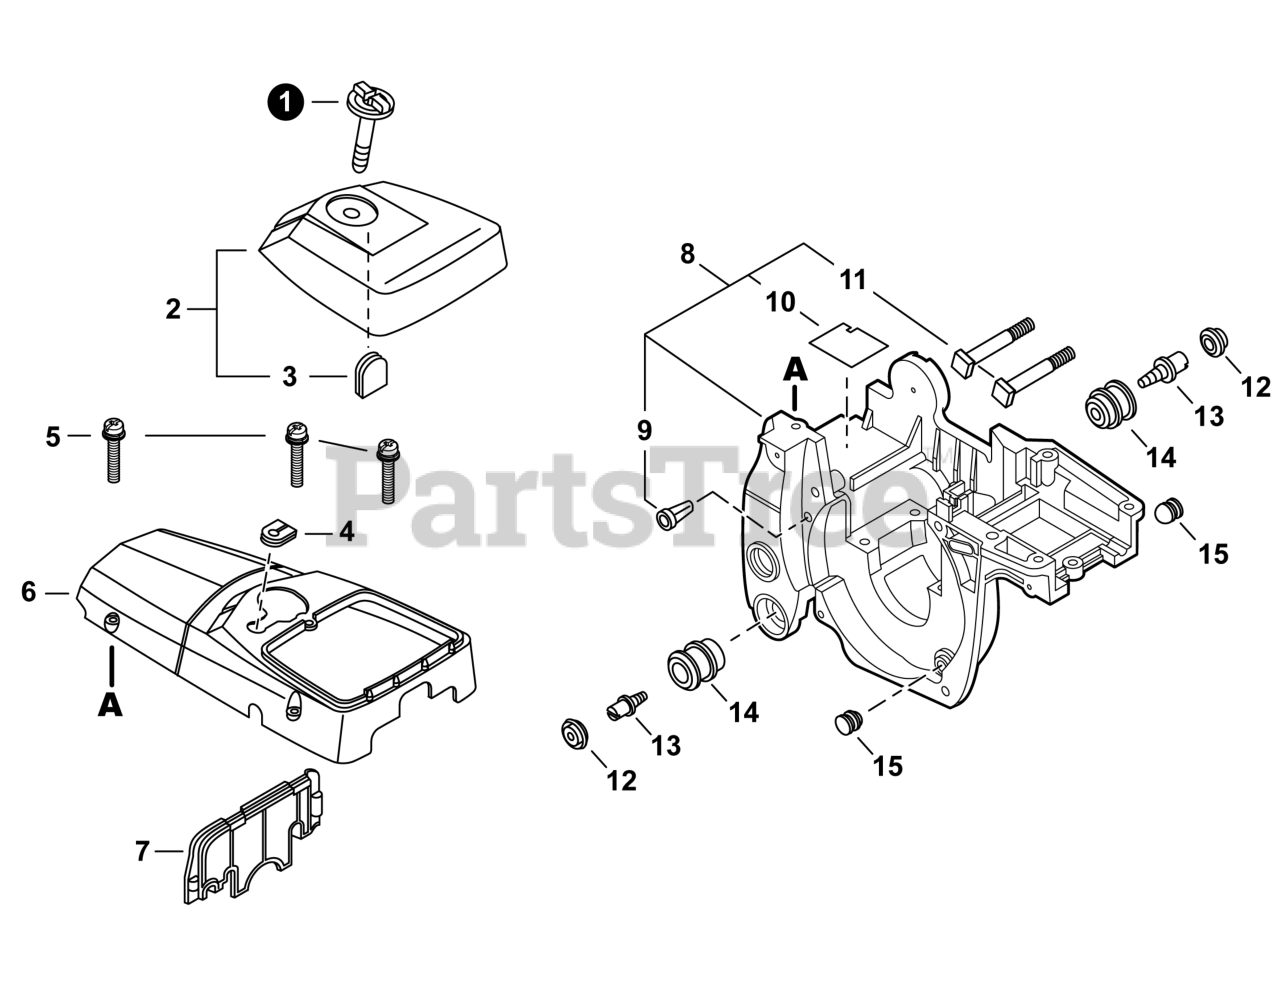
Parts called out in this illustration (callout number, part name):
1	THUMBSCREW
2	COVER ASSY, AIR FILTER
4	GROMMET
5	SCREW 5x20
6	COVER, ENGINE
7	PLATE, INSULATOR
8	COVER ASSY, ENGINE
9	VENT ASSY
10	SHIELD, HEAT
11	STUD, GUIDE BAR 8
12	CAP, CUSHION
14	CUSHION 5
15	CUSHION
